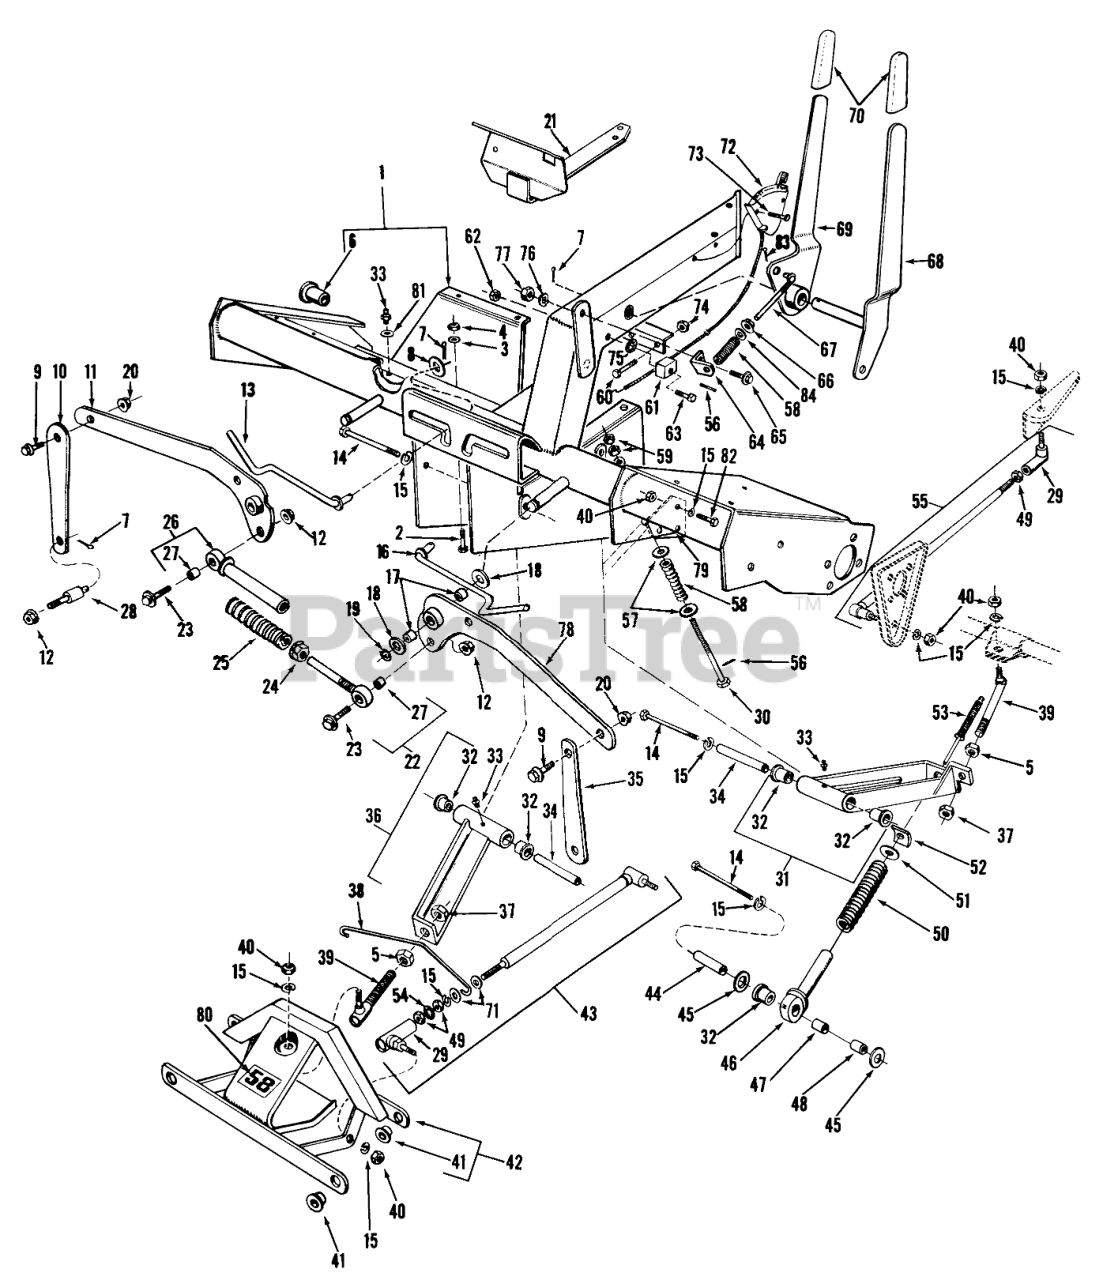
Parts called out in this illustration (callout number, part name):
2	SCREW-HH
3	WASHER-LOCK
4	NUT-HEX
5	NUT-LOCK, NI
6	3/4IDX1LG FLANGE BSHG
7	PIN-COTTER
8	WASHER-FLAT
9	SHOULDER BOLT
14	SCREW-HH
15	WASHER-LOCK
17	BUSHING
18	WASHER-FLAT
19	RING-RETAINING, EXTERNAL
20	NUT-LOCK
23	Shoulder Bolt
24	NUT-LOCK, FLANGE
27	BUSHING
29	Ball Joint End
32	BUSHING-FLANGE
33	FITTING-GREASE
37	NUT-JAM
38	Spring, Stabilizer
40	NUT-HEX
41	BUSHING-FLANGE
45	WASHER-FLAT
46	GUIDE BUSHING WA
47	SPLIT SPACER
49	NUT-HJ
50	COMPRESSION SPRING
52	ADJUSTING NUT
53	Anchor
54	WASHER-LOCK, INTERNAL
55	Ball Joint, Mower Hitch
56	PIN-ROLL, SLOTTED
57	WASHER-PLAIN
58	SPRING
59	NUT-HEX
60	SCREW-HH
61	REEL STOP
63	SCREW-HH
64	PIVOT BRACKET
65	IDLER SHOULDER SCREW
66	NUT-LOCK, INSERT
71	WASHER-FLAT
74	NUT-HEX
75	WASHER-LOCK
76	WASHER-LOCK
77	NUT-JAM
79	Anchor Plate
81	WASHER-LOCK
82	SCREW-HH
83	PIN-COTTER
84	WASHER-FLAT
